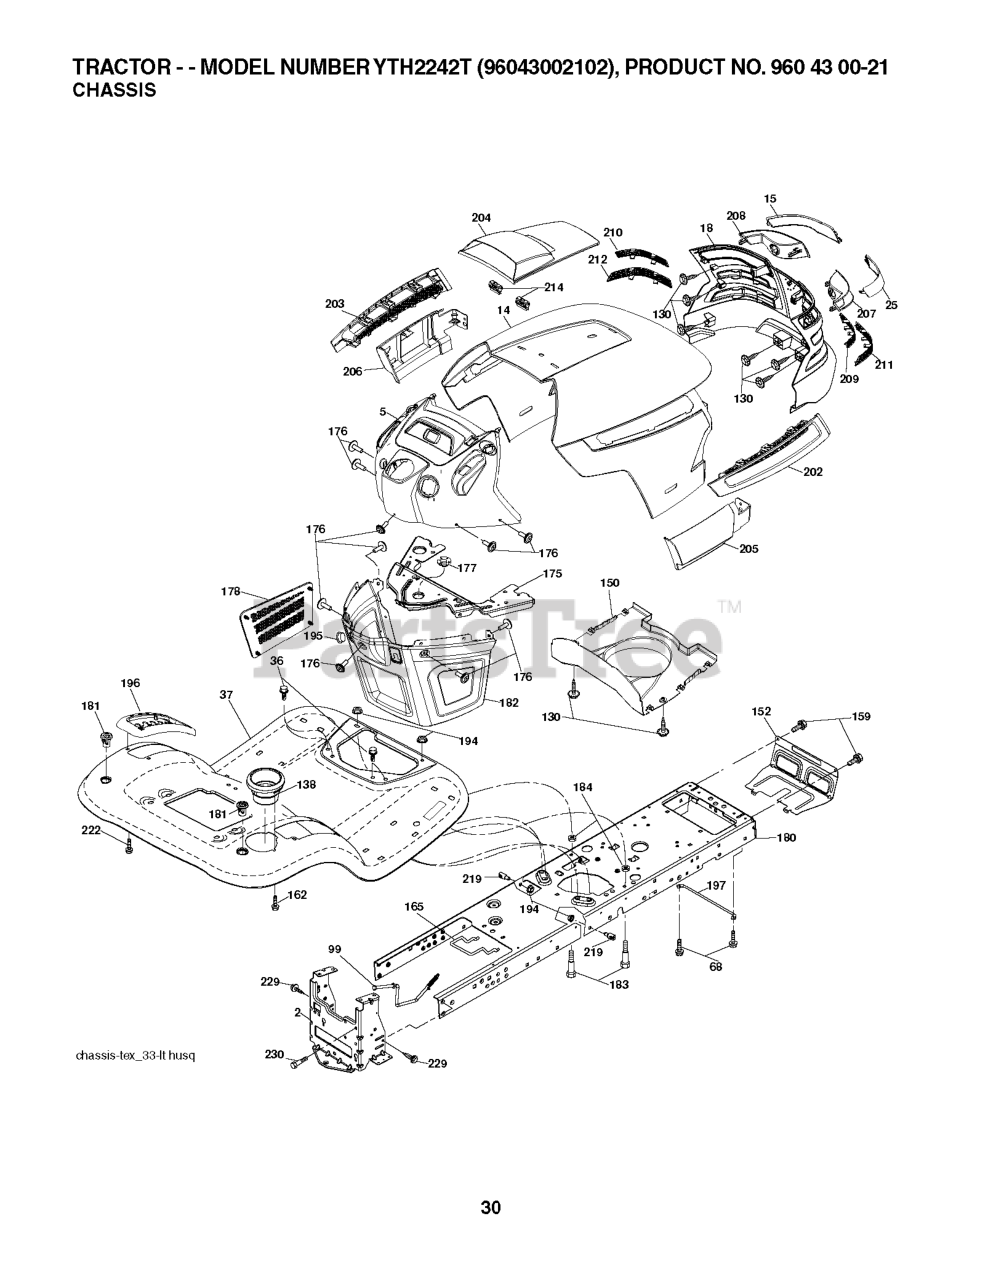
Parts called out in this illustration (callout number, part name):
2	DRAWBAR.1PC.NSTL
5	DASH.HUSQ.UPR.ELE.SVMD
14	HOOD.PNT.HUSQVARNA.GT.
15	LENS.LH.TEX.GT.HUSQ.CL
18	GRILLE.ASM.TEX.GT.HUSQ
25	LENS.RH.TEX.GT.HUSQ.CL
36	SCREW 5/16"
37	FEND/FTRST.PCH.CPH.FW
68	Screw 5/16-18 x 1/2 Hex, Self Tapping 5/16-18 x 1/2
99	ROD.BYPASS.ASM.0510.HY
130	SCREW
138	CUPHOLDER.TL.TEX.418
150	AIR.DUCT.TEXGT.HUSQ.SV
152	SHIELD.BROWNING/DEBRIS
159	SCREW, 3/8-16X3/4
162	SCREW.HI-LO.CONSOLE
165	SUPPORT.TANK.REAR.B/TE
175	PLATE.CROSSMEMBER.HUSQ
176	SCREW.#10-24X5/8.RN.QU
177	BUSHING, STEERING
178	CARGO.ASM.NET.TXGT.W/C
180	CHASSIS.STAMPING.LT/GT
181	BUSHING.MNT.FEND.CRGO.
182	DASH.LOWER.COMMON.12V.
183	BOLT.5/16-18X1-1/4 FULL.THREAD
184	SPACER.FENDER
194	NUT LOCK HEX FLANGE 5/16-18
195	PLUG.HOLE.DASH.LOWER.12V.BLK
196	CONSOLE.ASM.DECK.LIFT.
197	ROD PIVOT CHASSIS/HOOD
202	VENT.SIDE.HOOD.HUSQ.RH.GREY
203	VENT.SIDE.HOOD.HUSQ.LH.GRAY
204	VENT.TOP.HOOD.HUSQVARN
205	SKIRT.HOOD.SIDE.HUSQ.RH.GREY
206	SKIRT.HOOD.SIDE.HUSQ.LH.GREY
207	BEZEL.RH.TEX.GT.HUSQ
208	BEZEL.LH.TEX.GT.HUSQ
209	INSERT.HEX.GRILL.HUSQ.GREY
210	INSERT.HEX.GRILL.HUSQ.
211	INSERT.HEX.GRILL.HUSQ.
212	INSERT.HEX.GRILL.HUSQ.
214	CLIP.RETAINER.TINNER.
219	STUD.FASTNER.W/ANTI-ROTATE
222	SCREW.1/4-20X5/8
229	SCREW 3/8-16X1
230	SHOULDER BOLT 5/16-18TT
